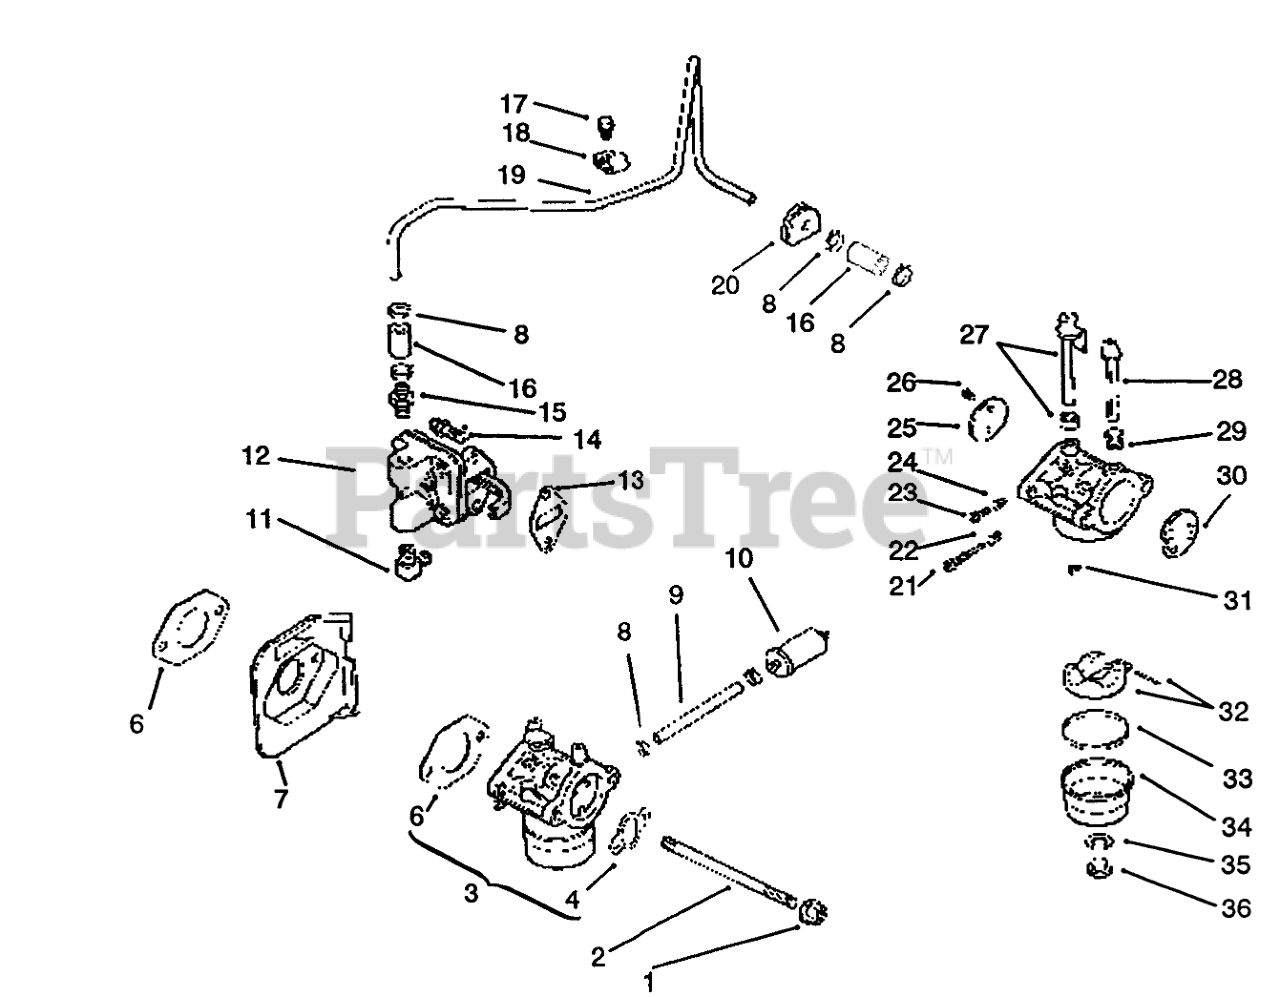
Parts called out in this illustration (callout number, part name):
1	Nut M6x1.0 (Only On: 72042, 72063, 72062, 72043)
2	Stud M6x1.0x110 (Only On: 72042 72063, 72062, 72043)
3	Kit-Carb INC 4/6/21-36 (Only On: 72042, 72063, 72062, 72043)
4	Gasket-Air Cleaner (Only On: 72042, 72063, 72062, 72043)
6	Gasket-Carburetor (Only On: 72042, 72063, 72062, 72043)
7	Deflector-Heat (Only On: 72042, 72063, 72062, 72043)
8	Clamp-Hose (Only On: 72042, 72063, 72062, 72043)
9	Line-Fuel 3" (Only On: 72042, 72063, 72062, 72043)
10	Filter-Fuel (Only On: 72042, 72063, 72062, 72043)
11	Connector-90 DEG (Only On: 72042, 72063, 72062, 72043)
12	Kit-Pump INC 13-14 (Only On: 72042, 72063, 72062, 72043)
13	Gasket-Fuel Pump (Only On: 72042, 72063, 72062, 72043)
14	Screw M6x1.0x20 (Only On: 72042, 72063, 72062, 72043)
15	Connector-Straight(Only On: 72042, 72063, 72062, 72043)
16	Line-Fuel 1.25 Inch (Only On: 72042, 72063, 72062, 72043)
17	Screw M5x0.8x10 (Only On: 72042, 72063, 72062, 72043)
18	Clamp-Fuel Line (Only On: 72042, 72063, 72062, 72043)
19	Line-Fuel (Only On: 72042, 72063, 72062, 72043)
20	Grommet (Only On: 72042, 72063, 72062, 72043)
21	Needle-Idle Fuel Adjust (Only On: 72042, 72063, 72062, 72043)
22	Spring-Idle Fuel (Only On: 72042, 72063, 72062, 72043)
23	Screw-Idle Speed Adjust (Only On: 72042, 72063, 72062, 72043)
24	Spring-Idle Fuel (Only On: 72042, 72063, 72062, 72043)
25	Plate-Throttle (Only On: 72042, 72063, 72062, 72043)
26	Screw-Throttle Plate (Only On: 72042, 72063, 72062, 72043)
27	Shaft-W/Lever & Seal (Only On: 72042, 72063, 72062, 72043)
28	Shaft-Choke (Only On: 72042. 72063, 72062, 72043)
29	Spring-Choke Return (Only On: 72042,72063, 72062, 72043)
30	Plate-Choke (Only On: 72042, 72063, 72062, 72043)
31	Jet-Main (Only On: 72042, 72063, 72062, 72043)
32	Kit-Float (Only On: 72042, 72063, 72062,72043)
33	Gasket-Bowl (Only On: 72042, 72063, 72062, 72043)
34	Bowl-Fuel (Only On: 72042, 72063, 72062, 72043)
35	Gasket-Bowl Screw (Only On: 72042, 72063, 72062, 72043)
36	Screw-Fuel Bowl (Only On: 72042, 72063,72062, 72043)
